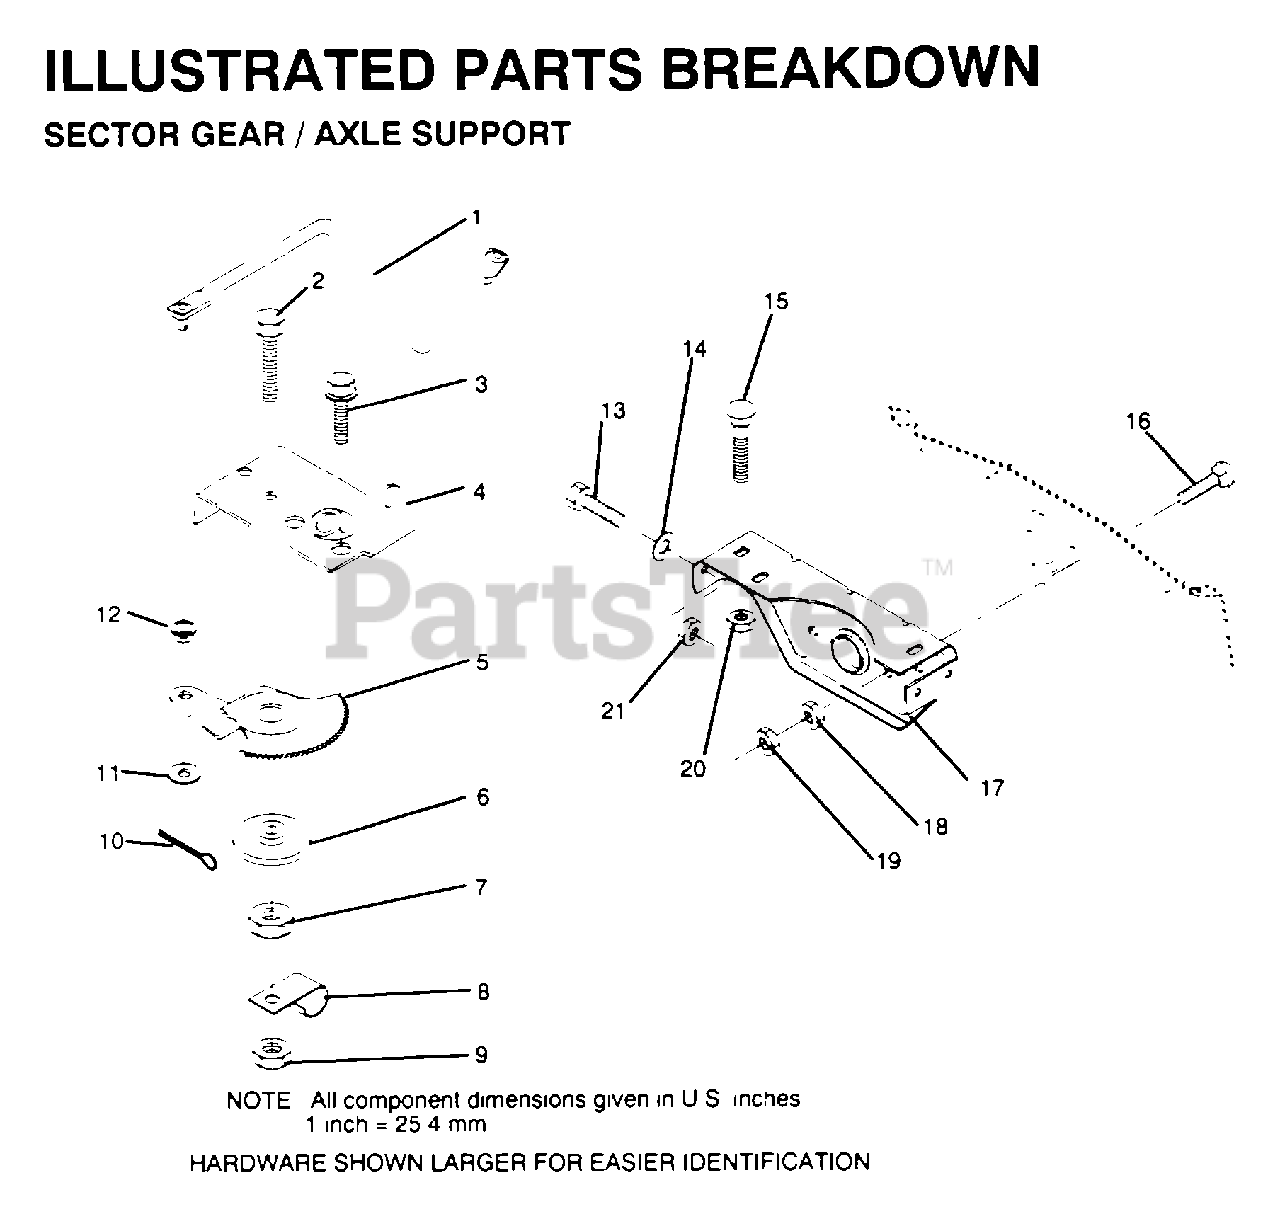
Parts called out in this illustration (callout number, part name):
2	"BOLT,HEX"
3	SCREW LT
4	"PLATE,STR SUPT"
5	GEAR SECTOR
6	BUSHING
7	NUT
8	CLIP INSULATOR
9	NUT LTV
10	COTTER PIN
11	WASHER
12	BUSHING.DRAGLINK
13	BOLT
14	WASHER
15	BOLT
16	BOLT
17	"SUPT,FRT AXLE"
18	NUT.HEX.3/8-16UNC
19	LOCKNUT
